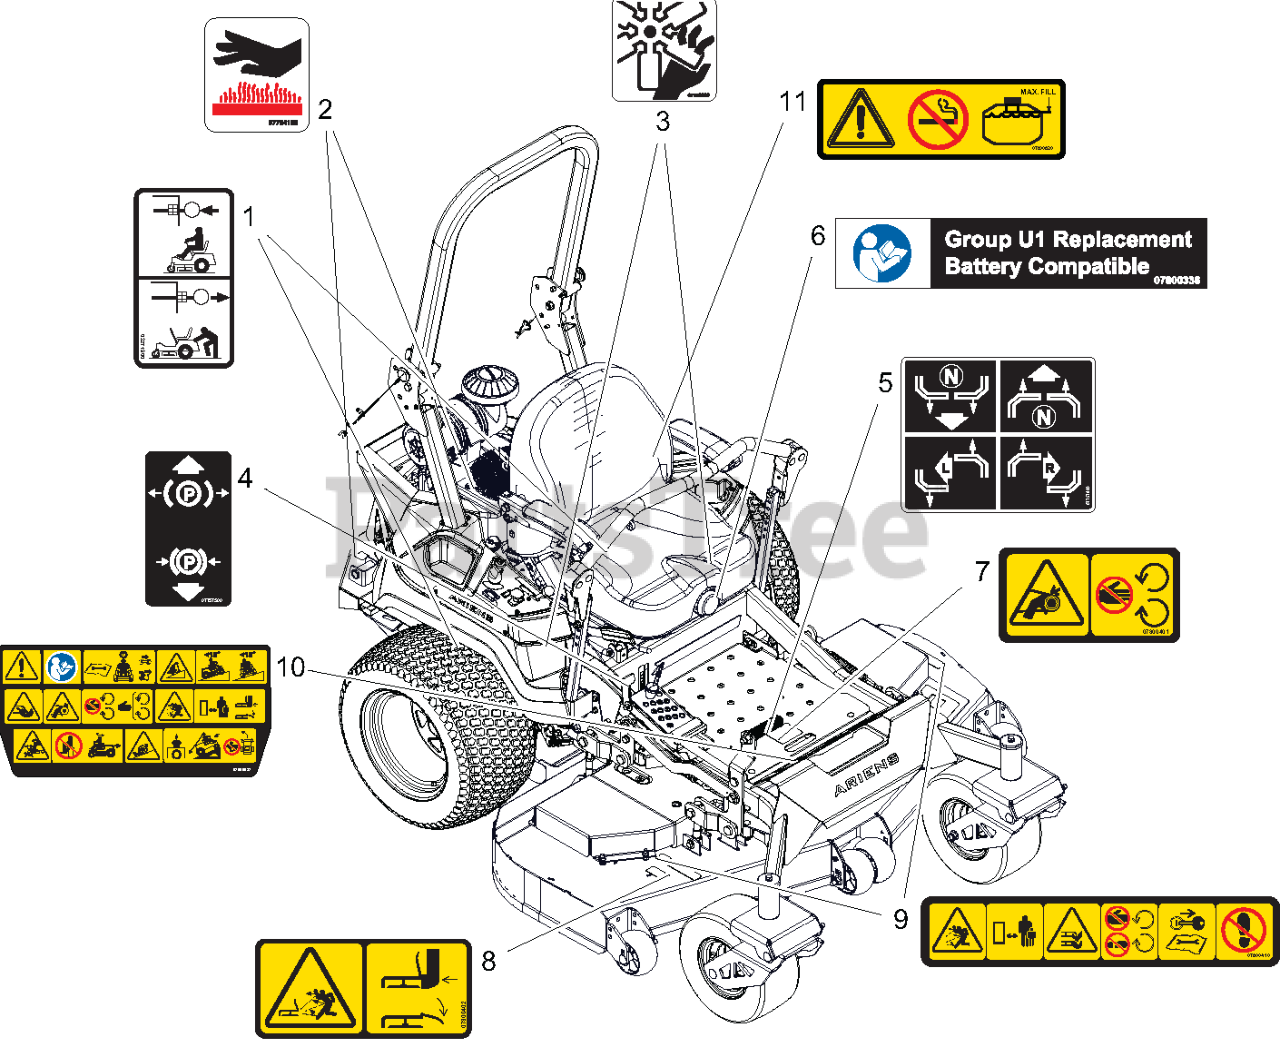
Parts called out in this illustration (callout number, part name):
1	DECAL, TRANSMISSION DISCONNECT
2	DECAL, HOT SURFACE
3	DECAL, DANGER FAN
4	DECAL, PARKING BRAKE LEVER
5	DECAL, INSTRUCTIONAL-STEERING
6	DECAL, U1 BATTERY REPLACEMENT
7	DECAL, SAFETY - GUARDING
8	DECAL, SAFETY - DECK GUARDING
9	DECAL, DECK SAFETY
10	DECAL, MAIN SAFETY
11	DECAL, FUEL WARNING
